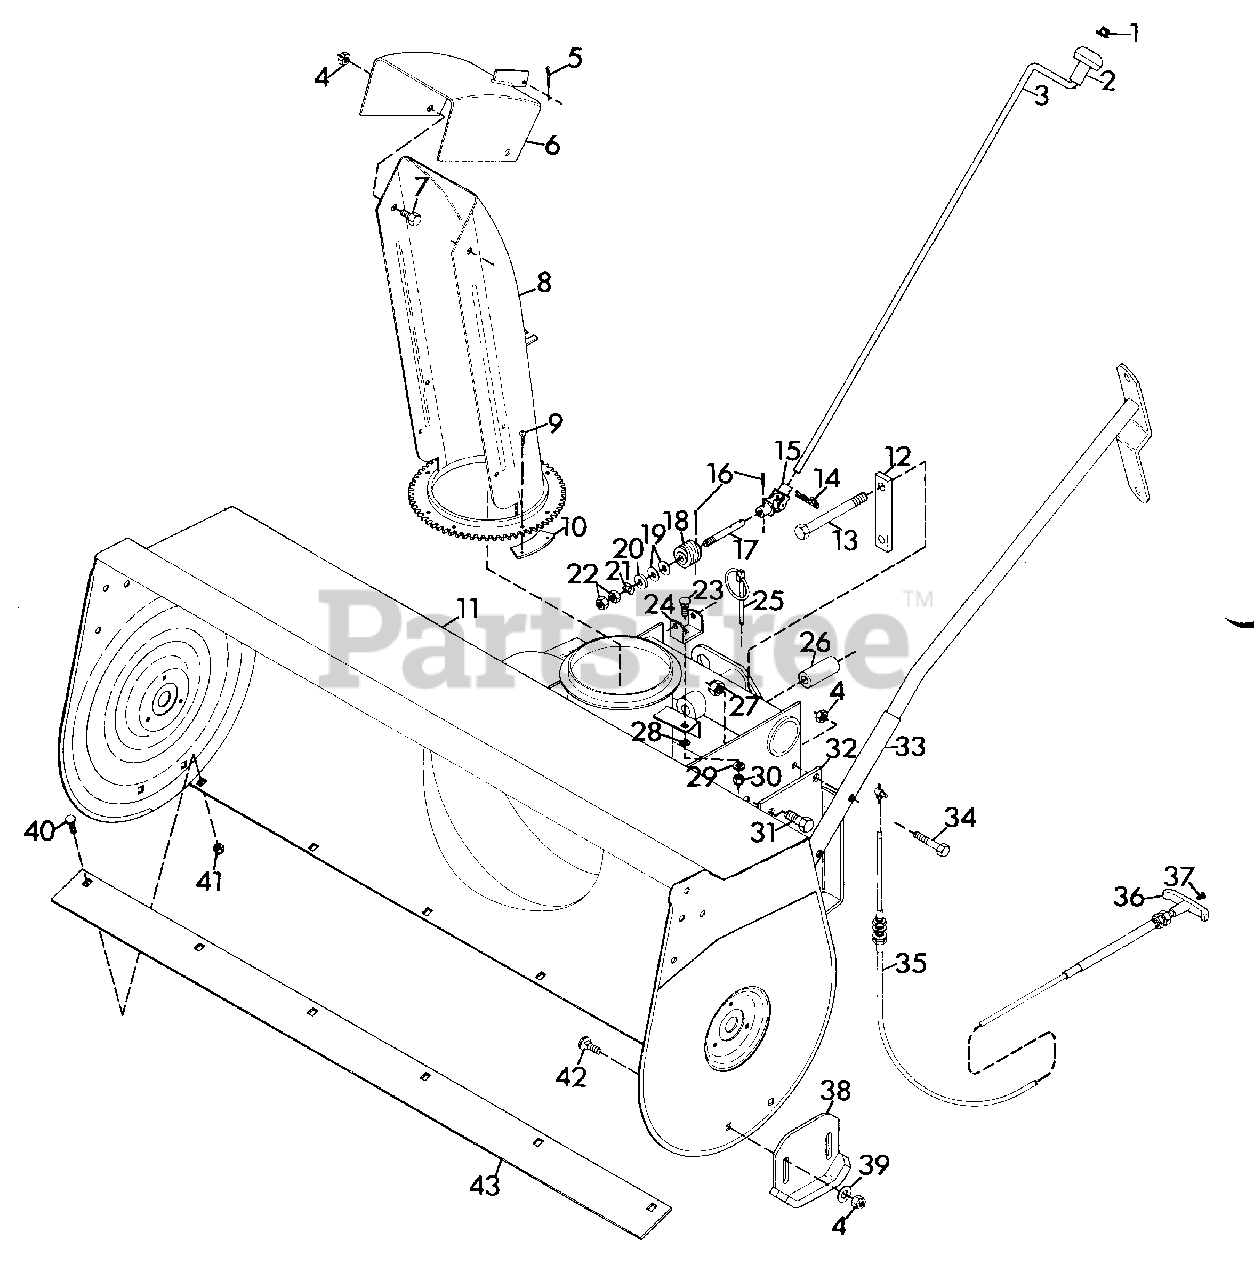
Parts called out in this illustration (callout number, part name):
1	CAP
2	KNOB
3	CRANK, CHUTE CONTROL
4	NUT, LOCK 3/8-16
5	PIN, COTTER .09X.75
6	CHUTE DEFLECTOR
7	BOLT, HEX 3/8-16X.75
8	DISCHARGE CHUTE
9	SCREW, TAPTITE #10-24X.375
10	CLAMP, CHUTE
11	32" SNO THRO HOUSING
12	STRAP, LOCKING
13	BOLT, HEX 1/2-13X4.50
14	HAIR PIN, INTERNAL
15	ASSEMBLY, U-JOINT
16	PIN, SPRING .125X.750
17	WORM SHAFT
18	WORM GEAR, L.H.
19	WASHER, PLASTIC .390X.875X.0
20	WASHER, .390X.875X.7 GA.
21	WAVE WASHER
22	NUT, JAM 3/8-16 HEX
23	BOLT, CARRIAGE 5/16-18X.75
24	WORM CLEVIS
25	PIN, SELF-LOCKING
26	SPACER
27	NUT, LOCK 1/2-13
28	WASHER, LOCK 3/8 EXT. TH. TYA
29	WASHER, LOCK 5/16 REG.
30	NUT, HEX 5/16-18
31	BOLT, HEX 1/2-13X1.25
32	BRACKET, SUPPORT
33	CRANK SUPPORT
34	BOLT, HEX 3/8-16X2.00
35	CABLE, CONTROL
36	HANDLE, TEE
37	SCREW, MACHINE 10-32X.50
38	RUNNER, SKID SHOE
39	WASHER, FLAT .406X.812X.065
40	BOLT, 5/16-18X.875 RD HD SQ NK
41	NUT, LOCK 5/16-18
42	BOLT, 3/8-16X1.00 RD HD SQ NK
43	SCRAPER BLADE
NS	DECAL, GRAVELY LOGO
NS	DECAL, DANGER FOOT
NS	DECAL, DANGER HAND
NS	DECAL, CHUTE
NS	DECAL, DEFLECTOR
